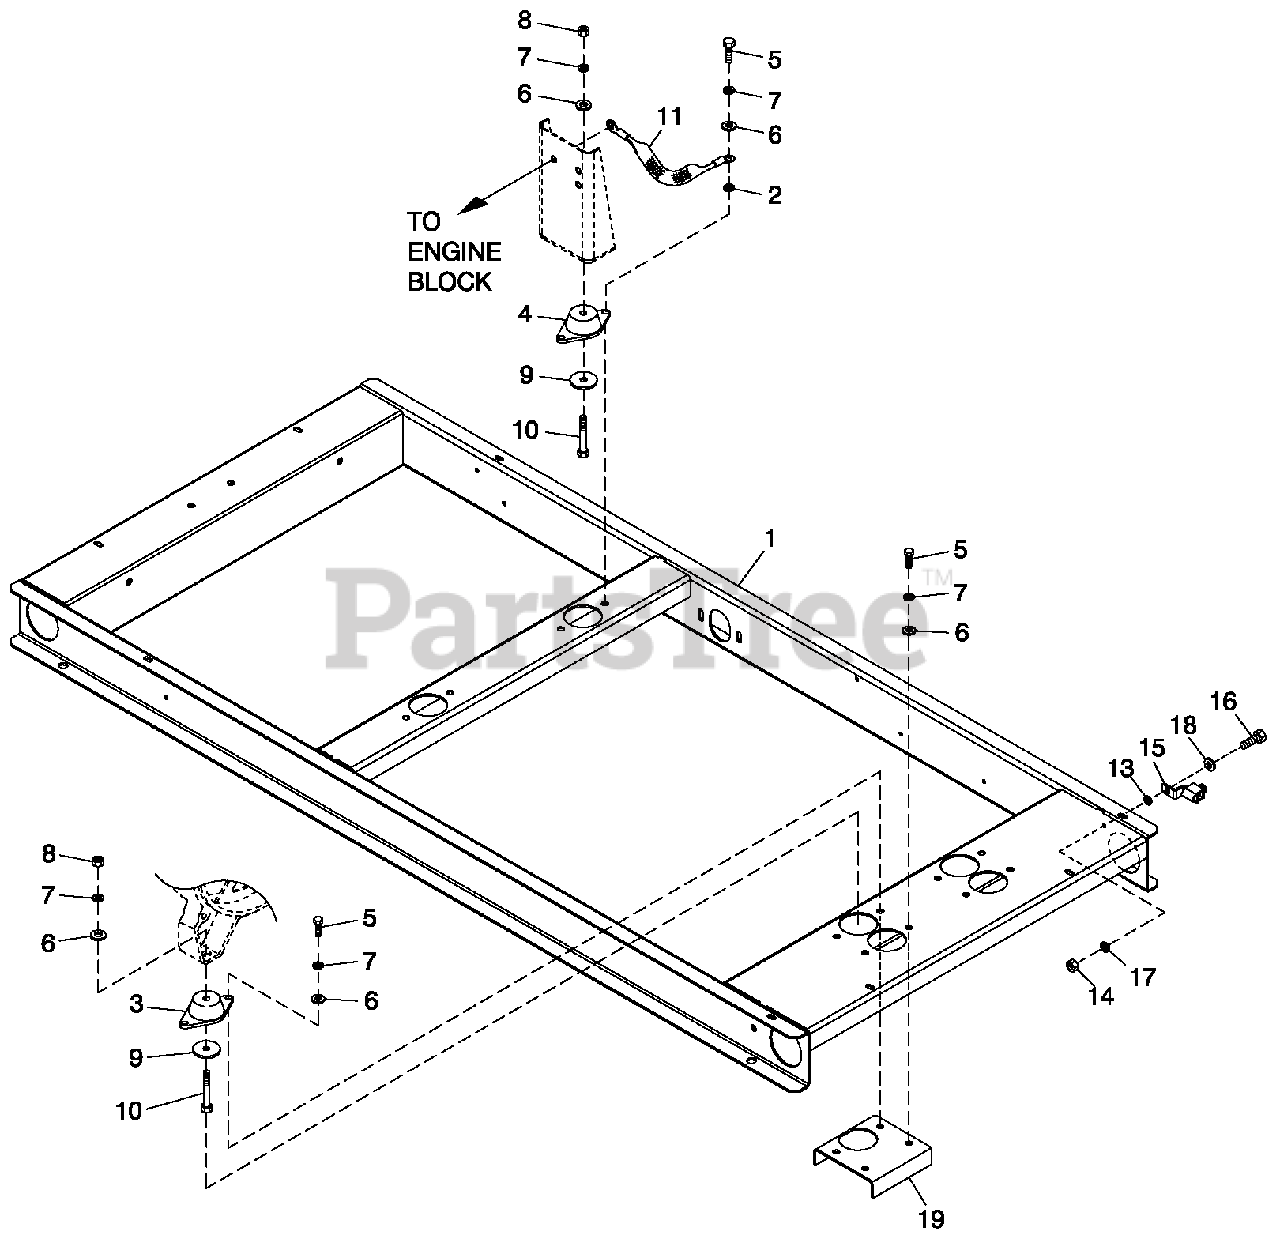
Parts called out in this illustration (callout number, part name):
1	MOUNTING BASE 1.6L 2007 C1
2	WASHER SHAKEPROOF EXT 5/16 STL
3	DAMPENER VIBRATION
4	VIB. ISO. 70-75 DURO
5	SCREW HHC M8-1.25 X 20 G8.8
6	WASHER FLAT 5/16 ZINC
7	WASHER LOCK M8-5/16
8	NUT HEX M 8-1.25 G8 YEL CHR
9	WASHER FLAT M8
10	SCREW HHC M8-1.25 X 60 G8.8
11	EARTH STRAP
13	WASHER SHAKEPROOF EXT 1/4 STL
14	NUT HEX M6 X 1.0 G8 YEL CHR
15	LUG SLDLSS #2-#8 X 17/64 CU
16	SCREW HHC M6-1.0 X 16 G8.8
17	WASHER LOCK M6-1/4
18	WASHER FLAT 1/4-M6 ZINC
